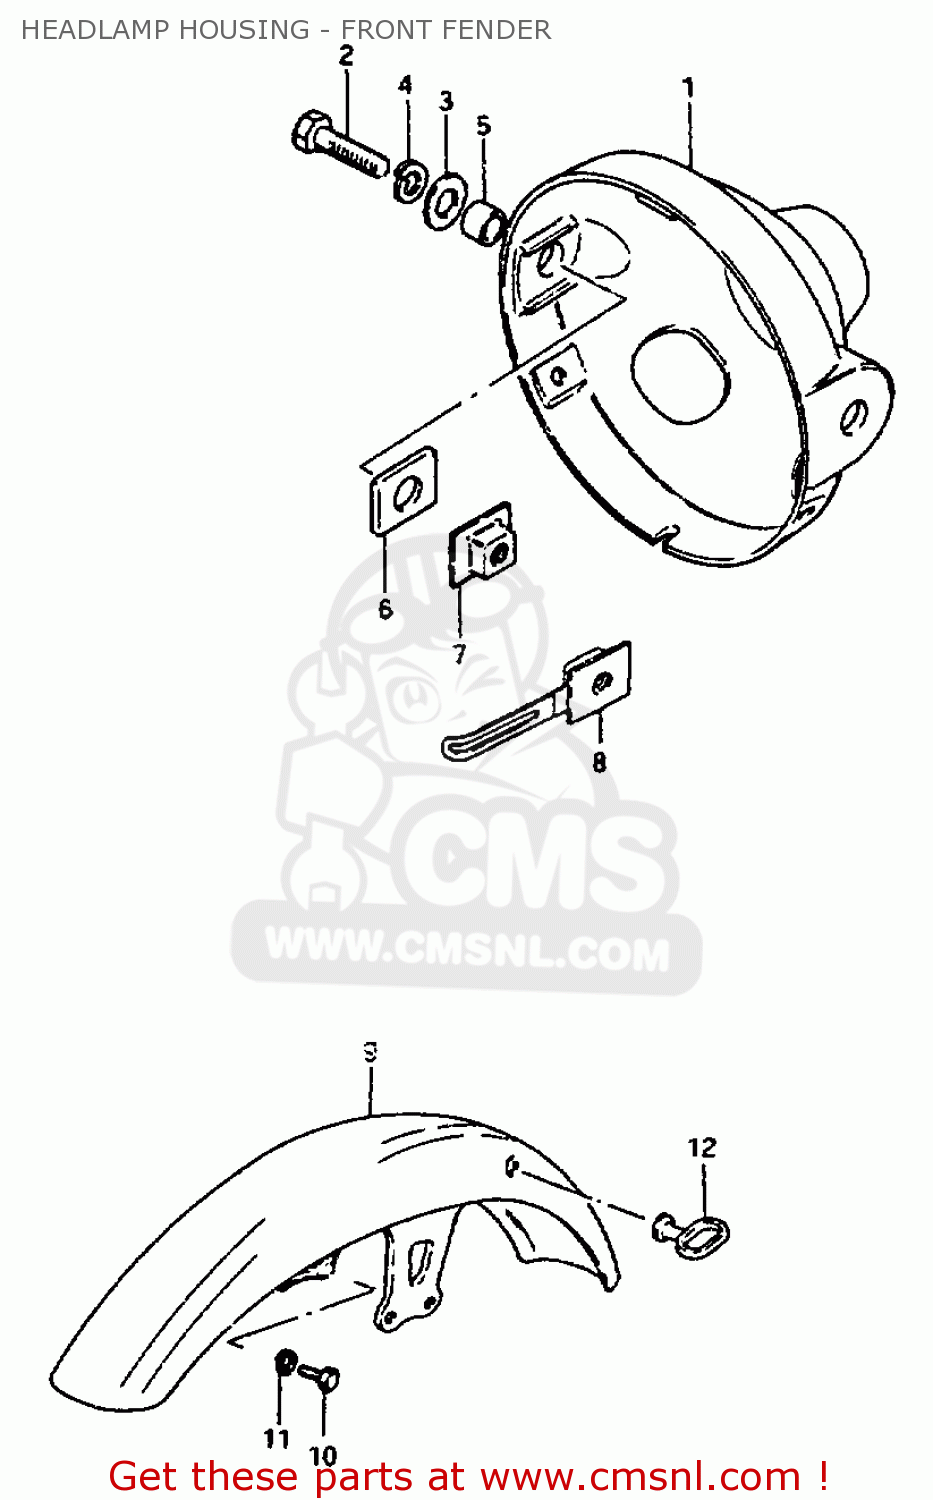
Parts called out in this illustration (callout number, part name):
1	HOUSING,HEADLAMP
2	BOLT
3	WASHER
4	LOCK WASHER
5	SPACER (8.8X12X7)
6	CUSHION
7	PLATE,HEADLAMP HOUSING
8	PLATE,HEADLAMP HOUSING
9	FENDER, FRONT
10	BOLT
11	LOCK WASHER
12	GUIDE,CABLE
